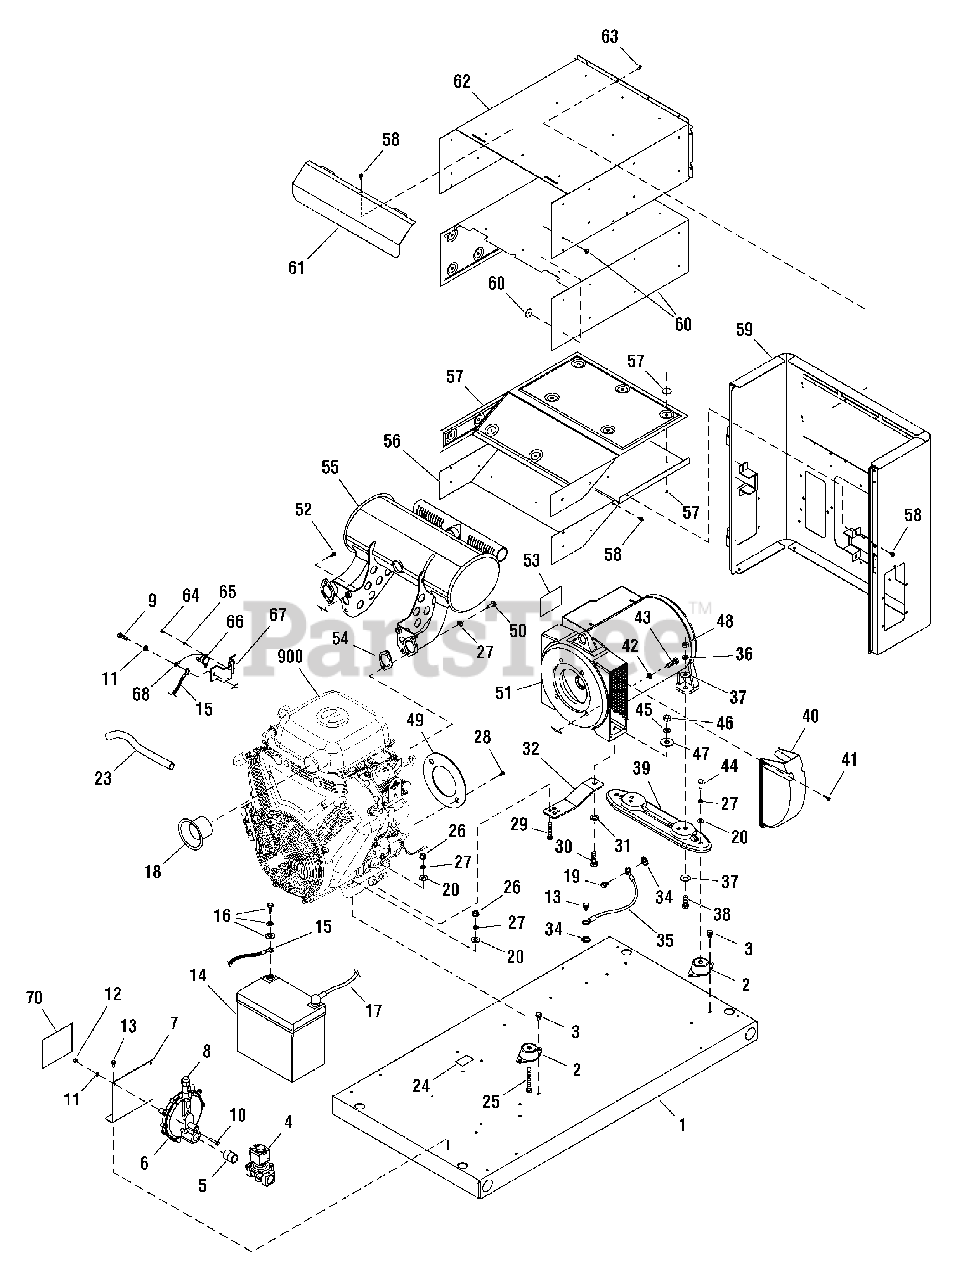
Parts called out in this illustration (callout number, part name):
2	MOUNT, Vibration
4	SOLENOID, Gas Fuel
6	REGULATOR, NG/LPG
7	BRACKET
9	* CAPSCREW, Hex Head, M6-1 x 16
10	* CAPSCREW, Hex Head, M6-1 x 30
11	* WASHER, Lock, 1/4
12	* NUT, M6-1
13	BOLT
15	CABLE, Battery, Black
16	KIT, Hardware, Battery
17	CABLE, Battery, Red
19	* CAPSCREW, Hex Head, M6 1 x 12
20	* WASHER, Flat, 5/16-M8
23	HOSE, Oil Drain
24	DECAL, Oil Drain
25	* CAPSCREW, Hex Head, 5/16-18 x 2-1/2
26	* NUT, 5/16-18
27	* WASHER, Lock, 5/16-M8
28	* CAPSCREW, Hex Head, SEMS, 5/16-24 x 3/4
29	* CAPSCREW, Hex Head, 5/16-18 x 2
30	* CAPSCREW, Hex Head, M12-1.75 x 35
31	* WASHER, M12
32	SUPPORT, Engine
34	* WASHER, Shakeproof, M6-1/4
36	* WASHER, Lock, M10
37	* WASHER, Flat, M10
38	* CAPSCREW, Hex Head, M10-1.5 x 30
39	SUPPORT, Alternator
41	* SCREW, Phillips Head, M5-0.8 x 20
42	* WASHER, Lock ,3/8
43	* CAPSCREW, 3/8-16 x 1-1/4
44	* CAPSCREW, Hex Head, 5/16-18 x 3/4
45	* WASHER, Lock, M12
46	* NUT, Hex, M12 - 1-3/4
47	* WASHER, Flat, M12
48	* NUT, M10 - 1-1/2
50	SCREW
51	ALTERNATOR, Complete
53	DECAL
59	BULKHEAD, Alternator
62	BOX, Muffler Top
64	* SCREW, Phillips Head, 4-40 x 0.19
65	* WASHER, Lock #4
66	SWITCH, Temp
67	PLATE, Temp Switch
900	** ENGINE
